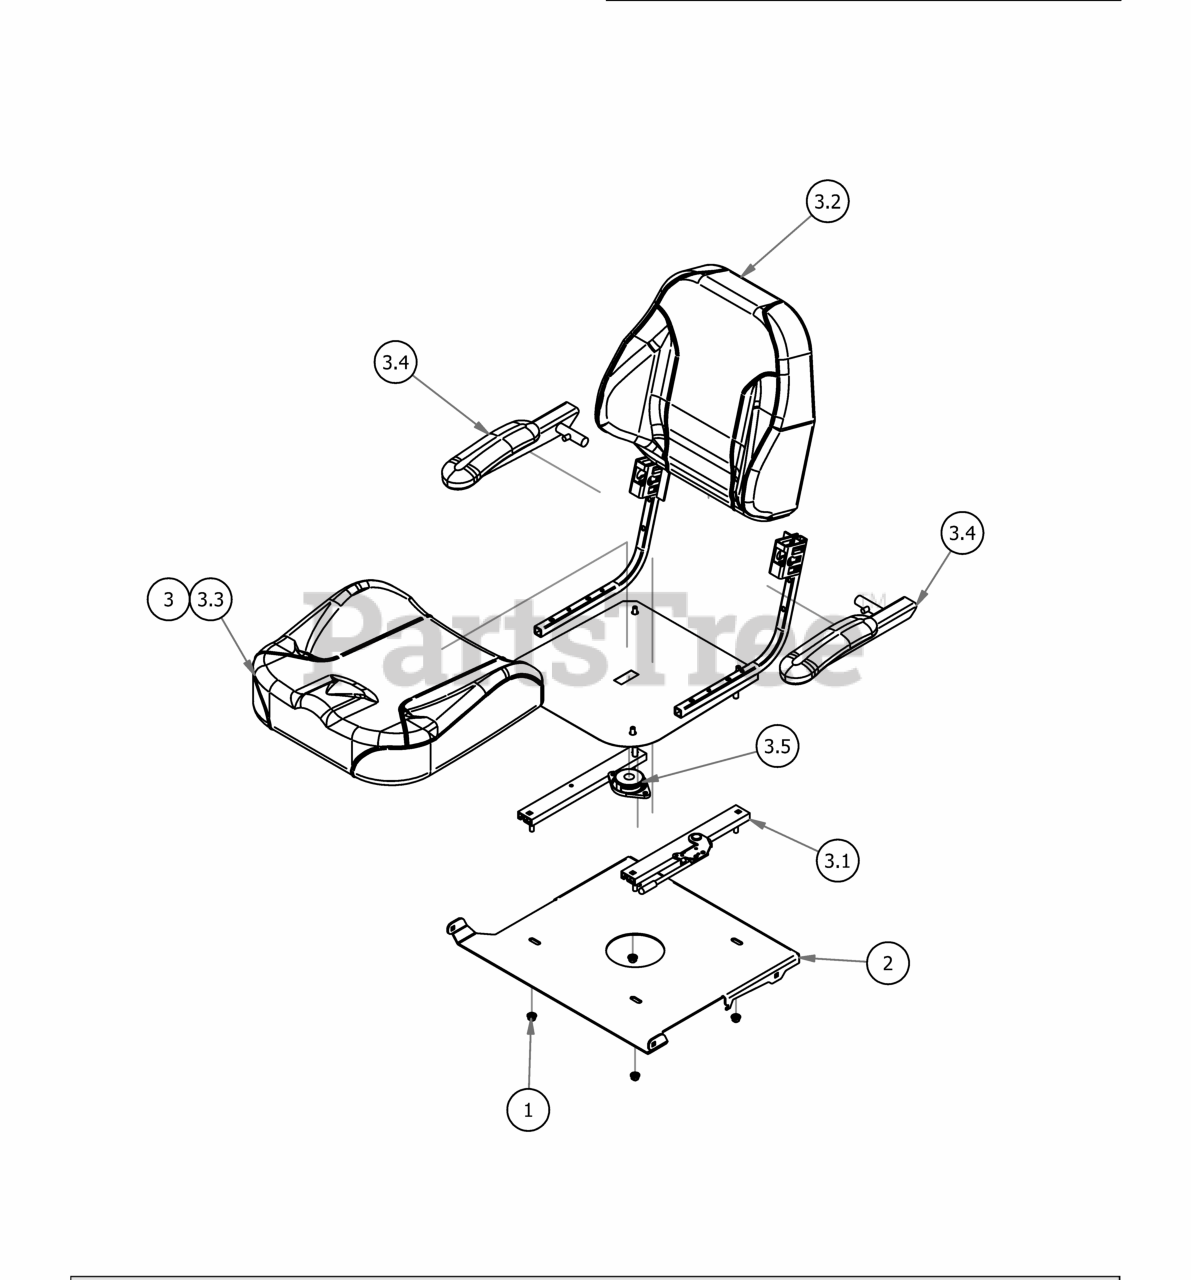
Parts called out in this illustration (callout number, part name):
1	5/16" Nylon Flange Nut
2	Seat Plate 2016
3	2018 ZT Seat
3.1	Seat Rail Pair
3.2	Seat Back Cushion
3.3	Seat Bottom Cushion
3.5	Seat Safety Switch
